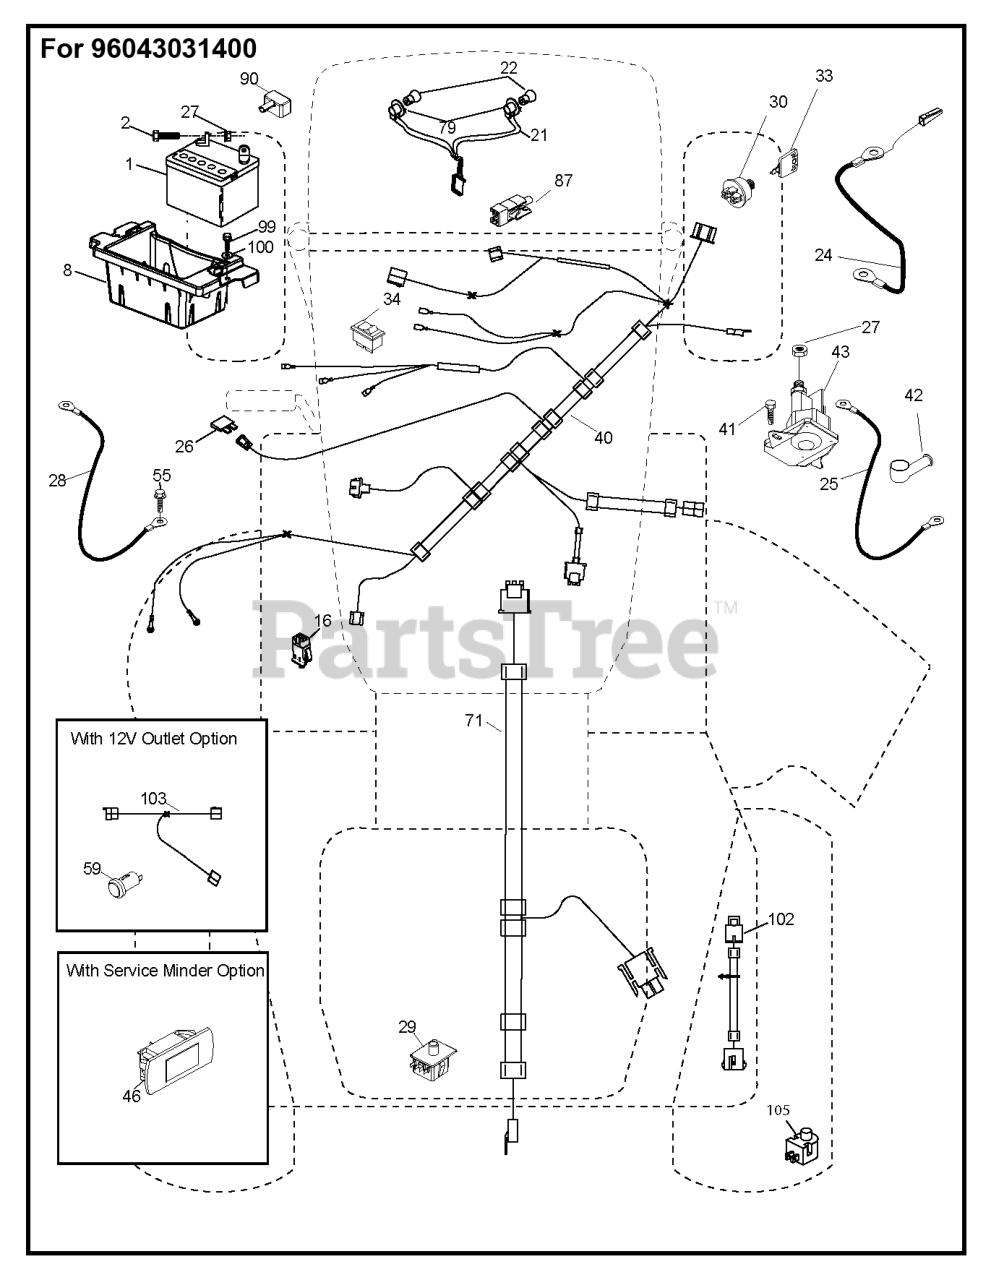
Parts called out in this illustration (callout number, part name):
1	Battery 12 Volt 25 Amp
2	BOLT.HEX.1/4.X.3/4.DICHROMATE
8	TRAY.BATTERY BOX.FRONT
16	SWITCH INTERLOOK PUSH-IN
21	HARNESS.LIGHT W/4152J BULBS
24	CABLE.FRBATT.W/WIRE.8GA.8
25	CABLE.STARTER.8GA.17.5
26	FUSE 20AMP
28	CABLE.GROUND.21"BLK.8GA.90T
29	SWITCH.SEAT.DP W/RAMPS
30	SWITCH.IGN.DELTA.W.LGH.ROS
33	KEY.CHAIN.BLISTER.PACK.GEN.USA
40	HARNESS.IGN.DASH.CBL.YTGT.PRED
41	SCREW
42	TERMINAL COVER
46	GUAGE.SRVCMNDR.HRMTR.
55	SCREW 5/16"
71	HARNESS-CHASSIS SUB
79	BULB HOLDER ASM.
87	SWITCH.INTRLCK.CLUTCH.
90	COVER.TERMINAL.BATTERY
99	SCREW HEXWSHR 1/4-20X3/4
102	HARNESS PIGTAIL PCH TEX ROS
105	REVERSE SWITCH
